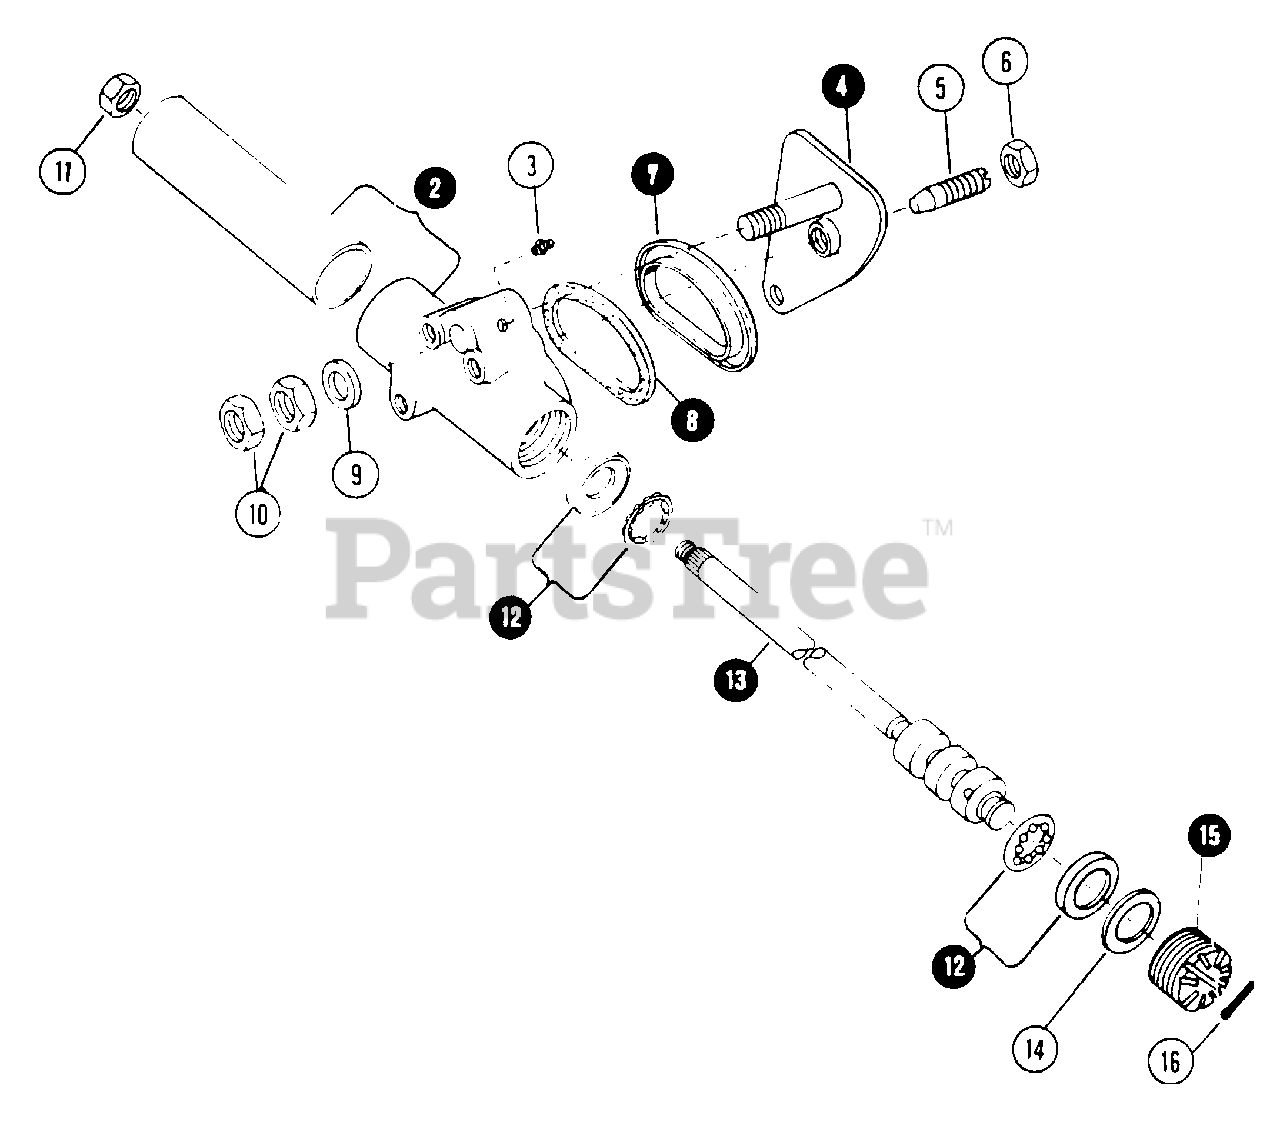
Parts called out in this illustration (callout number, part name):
2	HOUSING, STEERING GEAR
3	FITTING, GREASE 1/4 STRAIGHT DRIVE
4	LEVER, STEERING
5	STUD, STEERING LEVER ADJUSTING
6	NUT, 9/16F HEX
7	RETAINER, STEERING LEVER ADJUSTING
8	SEAL, STEERING LEVER
9	WASHER, STEERING LEVER
10	NUT, 3/4F HALF HEX
11	NUT, 5/8F HEX
12	KIT, BEARING REPLACEMENT
13	CAM-TUBE ASSEMBLY
14	WASHER, BELLEVILLE
15	PLUG, CAM-TUBE ADJUSTING
16	COTTER-PIN, 1/8 x 1/2
